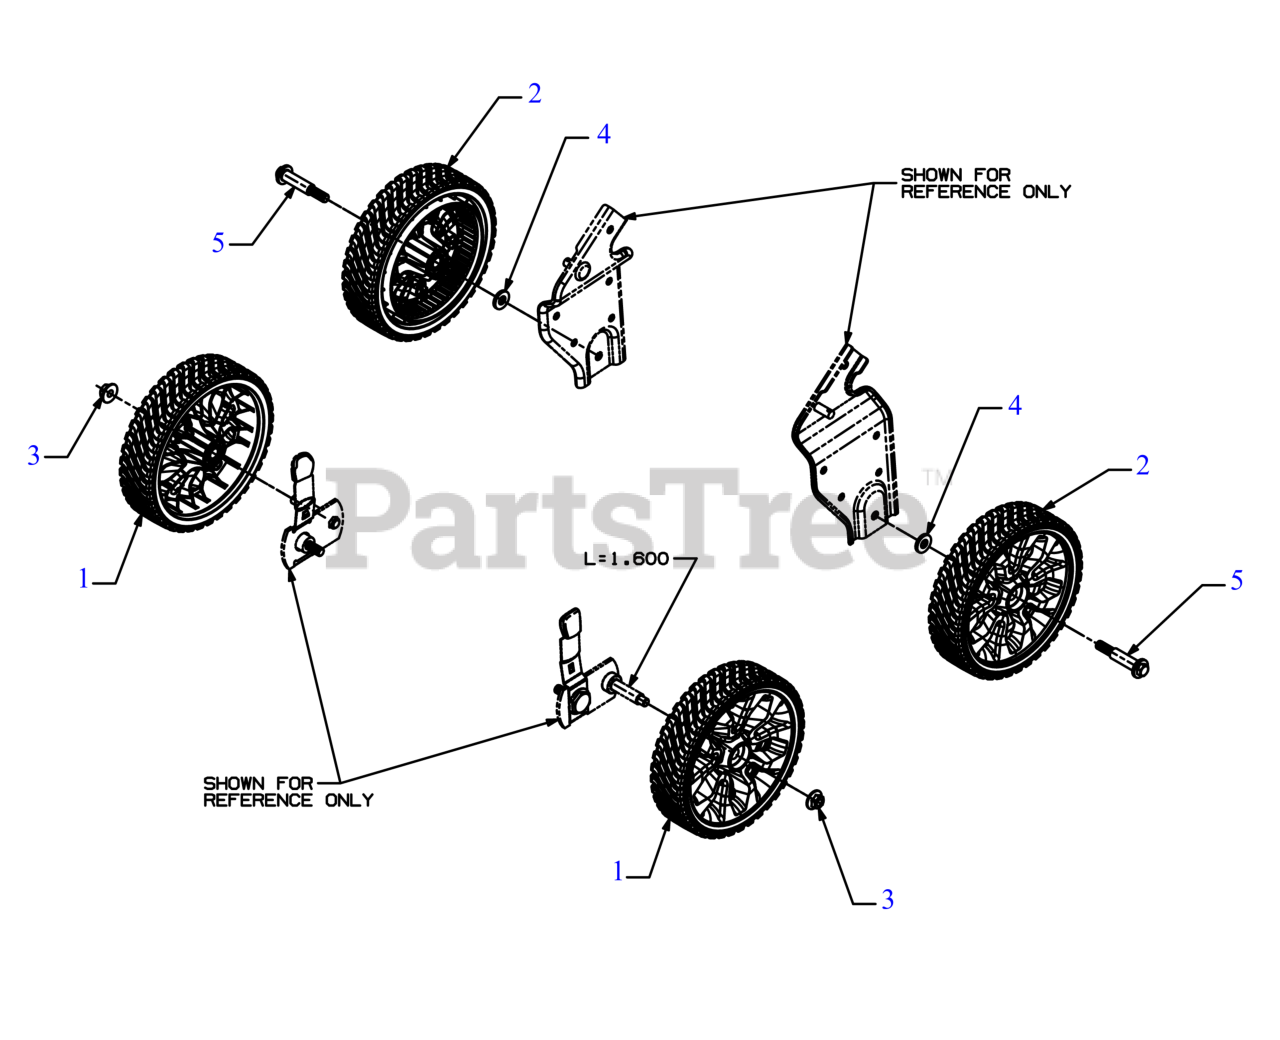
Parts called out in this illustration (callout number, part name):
1	WHEEL ASSEMBLY 8 x 2 GRAY
2	DRIVE WHEEL ASSEMBLY 8 X 2 GRAY
3	FLANGE LOCK NUT
4	FLAT WASHER
5	SHOULDER SCREW .496X1.605 3/8-16
